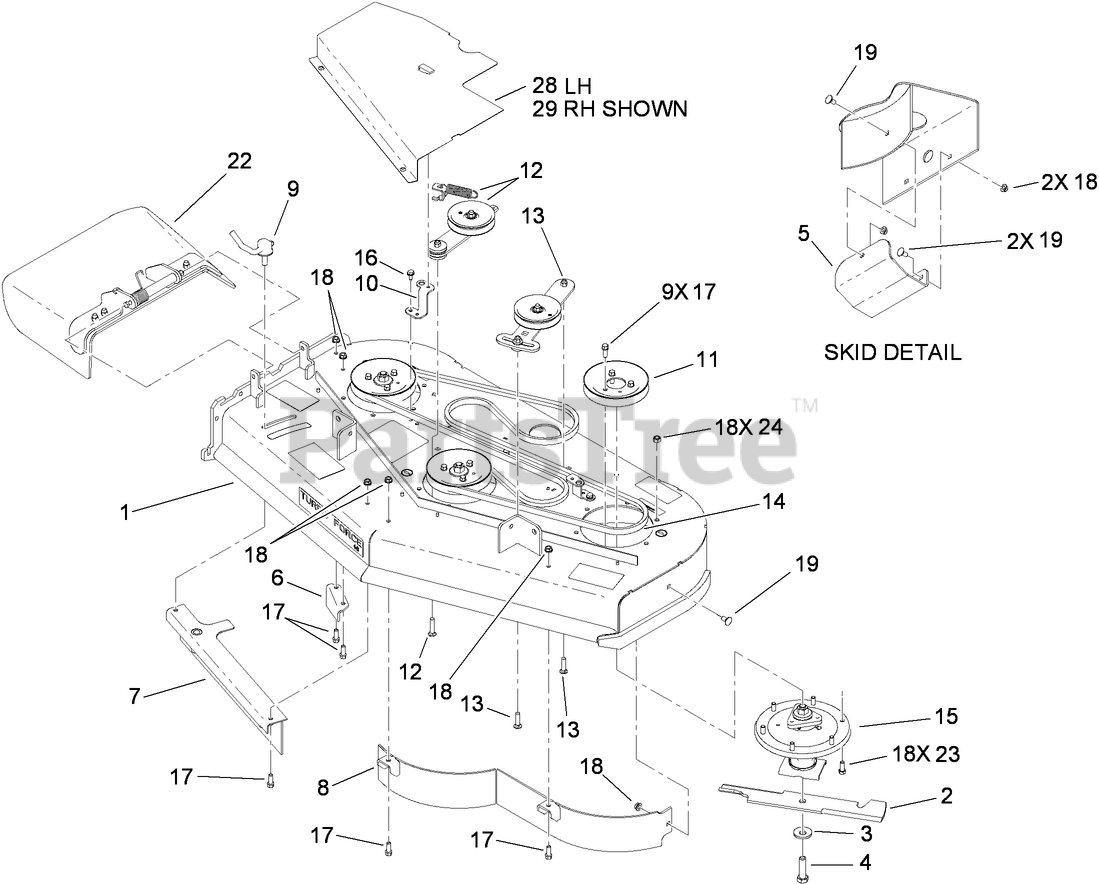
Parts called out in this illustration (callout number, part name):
1	DECK ASM
2	BLADE-16.5 INCH (HIGH FLOW)
3	Washer-Blade Bolt, Heavy
4	Screw-Cap
6	BAFFLE-DISCHARGE
8	48 INCH BAFFLE ASM
9	LEVER ASM
10	BRACKET-COVER, TALL
11	PULLEY
12	SPRING IDLER ASM
13	IDLER ADJUST ASM
14	BELT-V
15	SPINDLE ASM
16	SCREW-HWHTF
17	SCREW-HWH
18	NUT-HHF, WHIZ
19	SCREW-CARR
22	DEFLECTOR ASM
23	SCREW-HH
24	NUT-LOCK, NI
28	LH BELT COVER ASM
29	RH BELT COVER ASM
